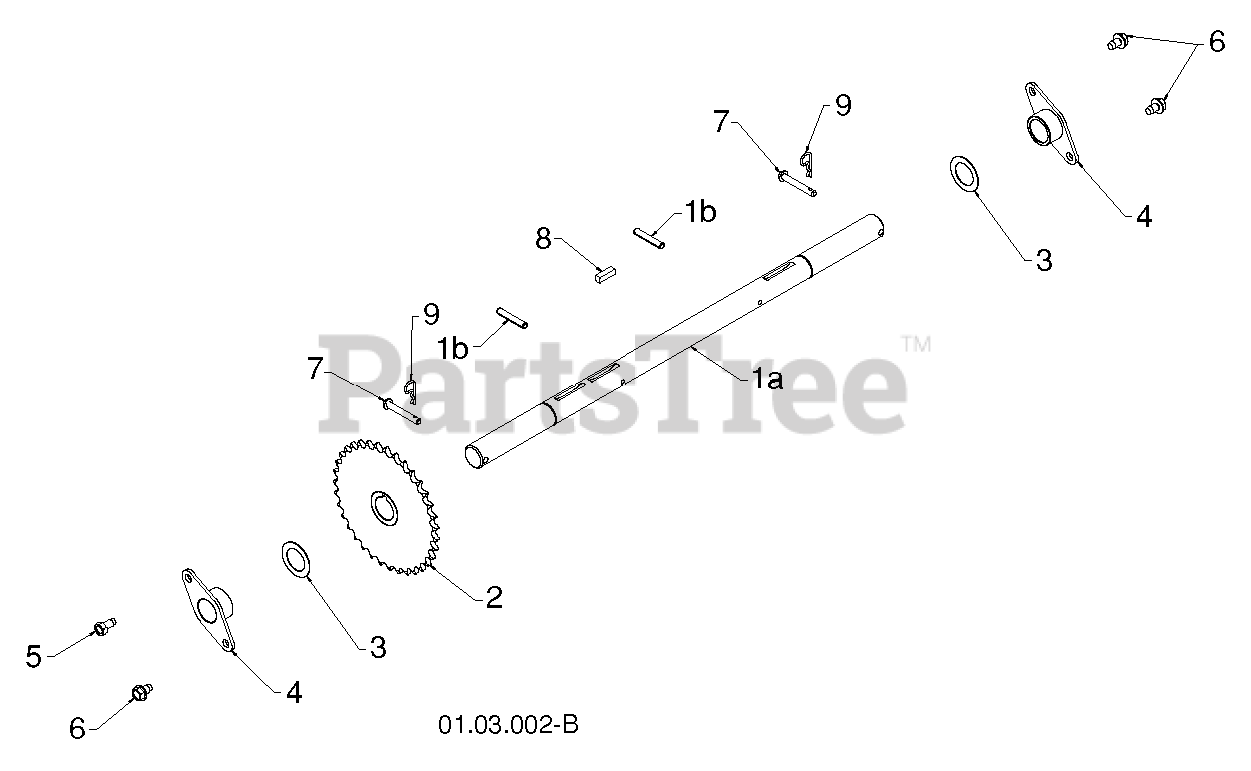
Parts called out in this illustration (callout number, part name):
2	SPROCKET.WELDMENT.AXLE.1.00
3	WASHER 1.00
4	BEARING, AXLE
6	Screw 5/16-18 x 1/2 Hex, Self Tapping 5/16-18 x 1/2
7	RIVET
8	KEY, SQUARE 1/4 X .875
9	RETAINER M
